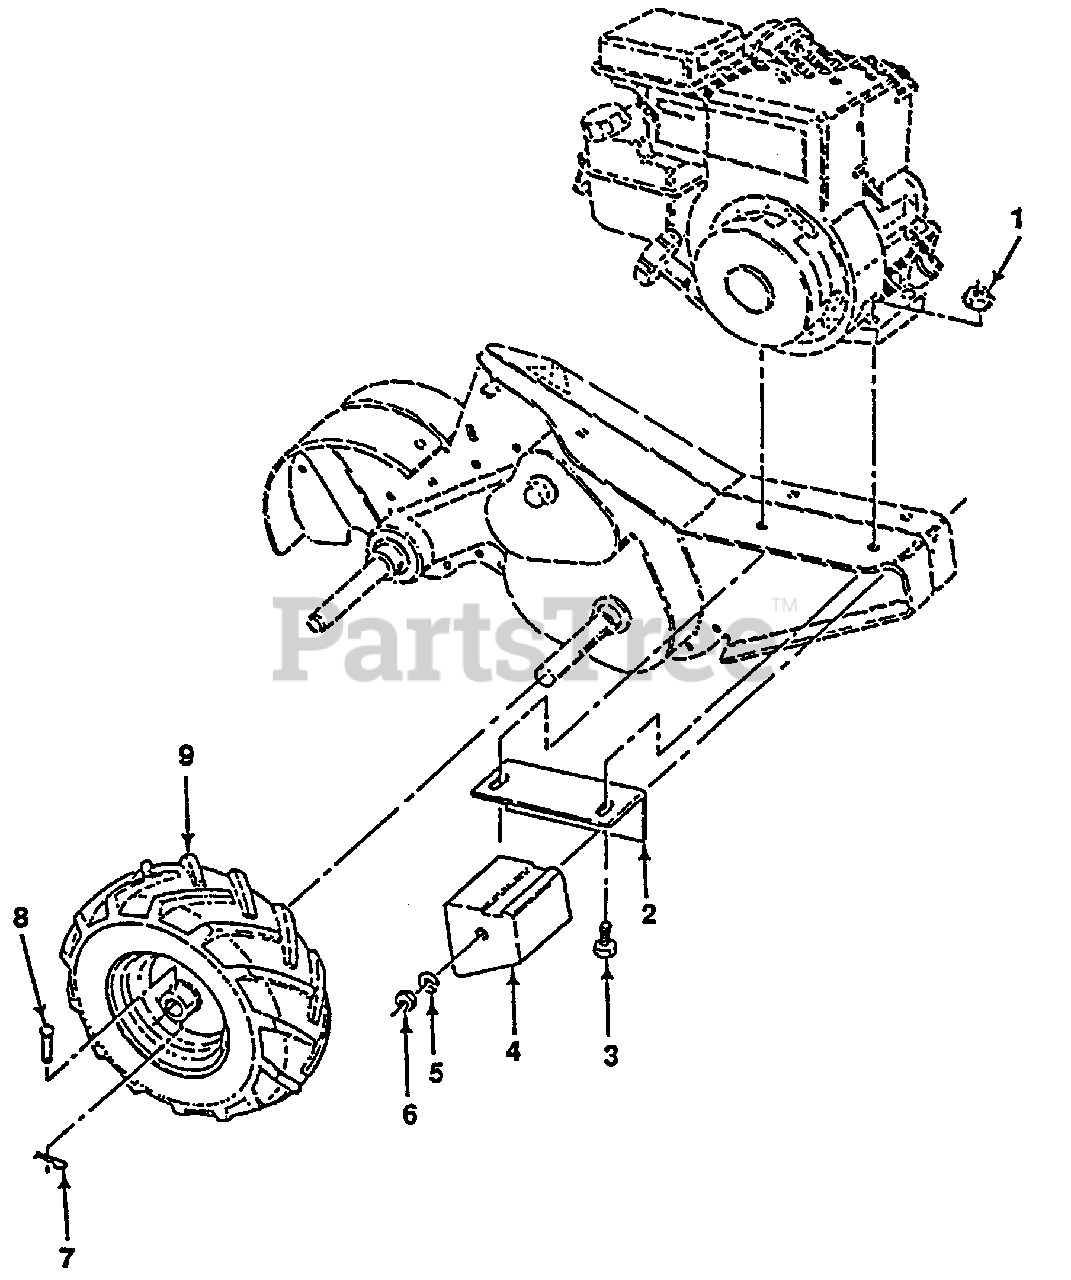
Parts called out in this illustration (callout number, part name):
1	Nut, Keps 5/16-18
2	Bracket, Reinforcment
3	Bolt, Hex 5/16-18 x 1-1/2
4	Counter Weight, R.H.
5	Washer, Lock 3/8
6	Nut, Hex 3/8-16
7	Clip, Hairpin
8	Rivet, Drilled
9	Tire Valve
